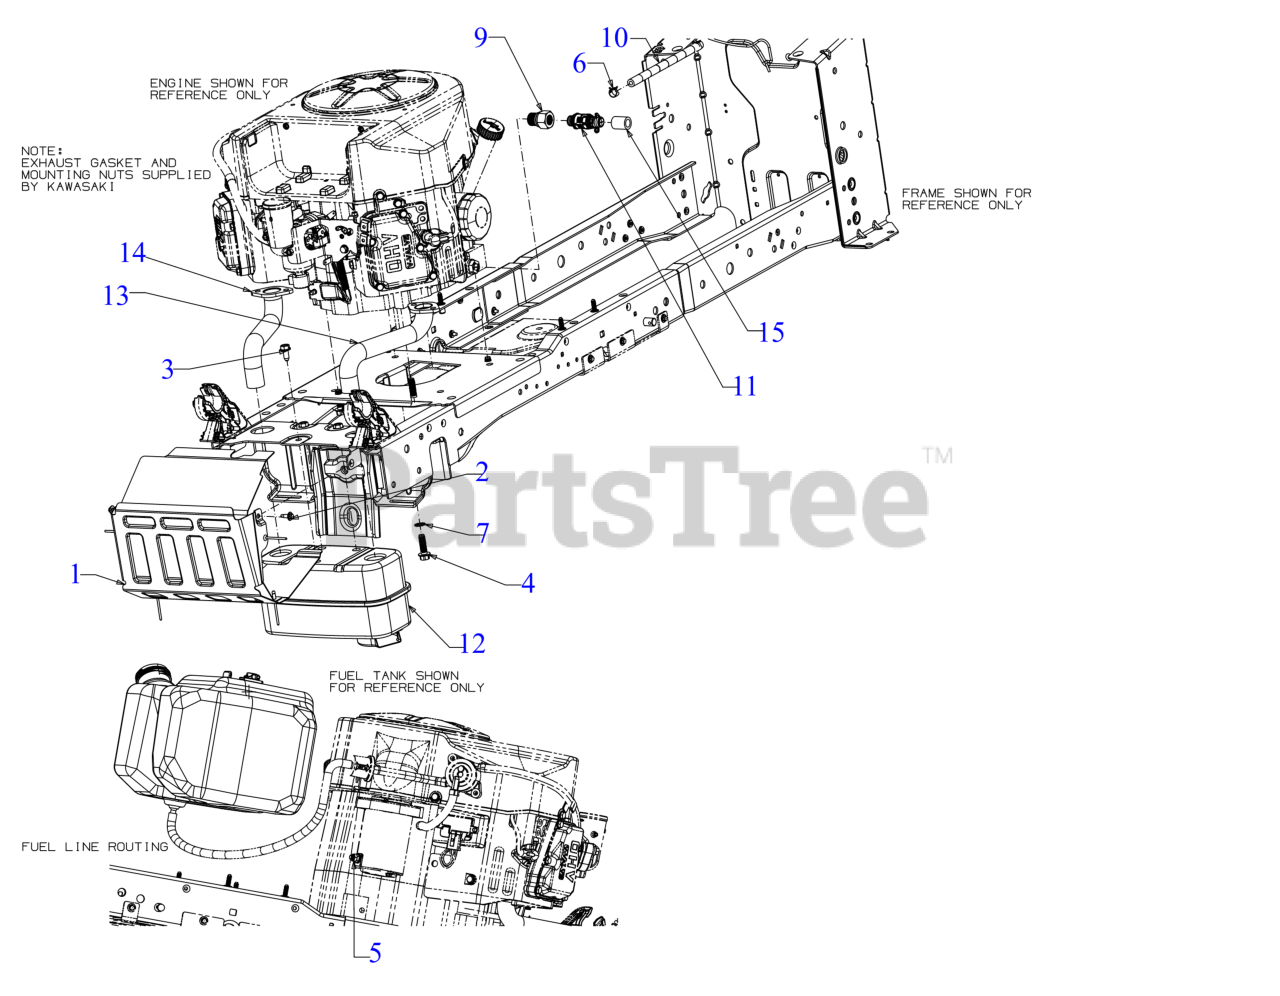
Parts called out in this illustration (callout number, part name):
1	MUFFLER SHIELD ASSEMBLY
2	SCREW M6-1 x .625
3	SCREW M8-1.25 x .750
4	SCREW 3/8-16 X1.250
5	HEX NUT 1/4-20
6	HOSE CLAMP 1/20
7	LOCK WASHER 3/8
9	OIL DRAIN FITTING
10	FUEL HOSE LOW PERMEATION 13"
11	OIL DRAIN VALVE
12	EXHAUST MUFFLER TWIN
13	EXHAUST PIPE (LH) (KAWASAKI)
14	EXHAUST PIPE (RH) (KAWASAKI)
15	DRAIN HOSE 14''
